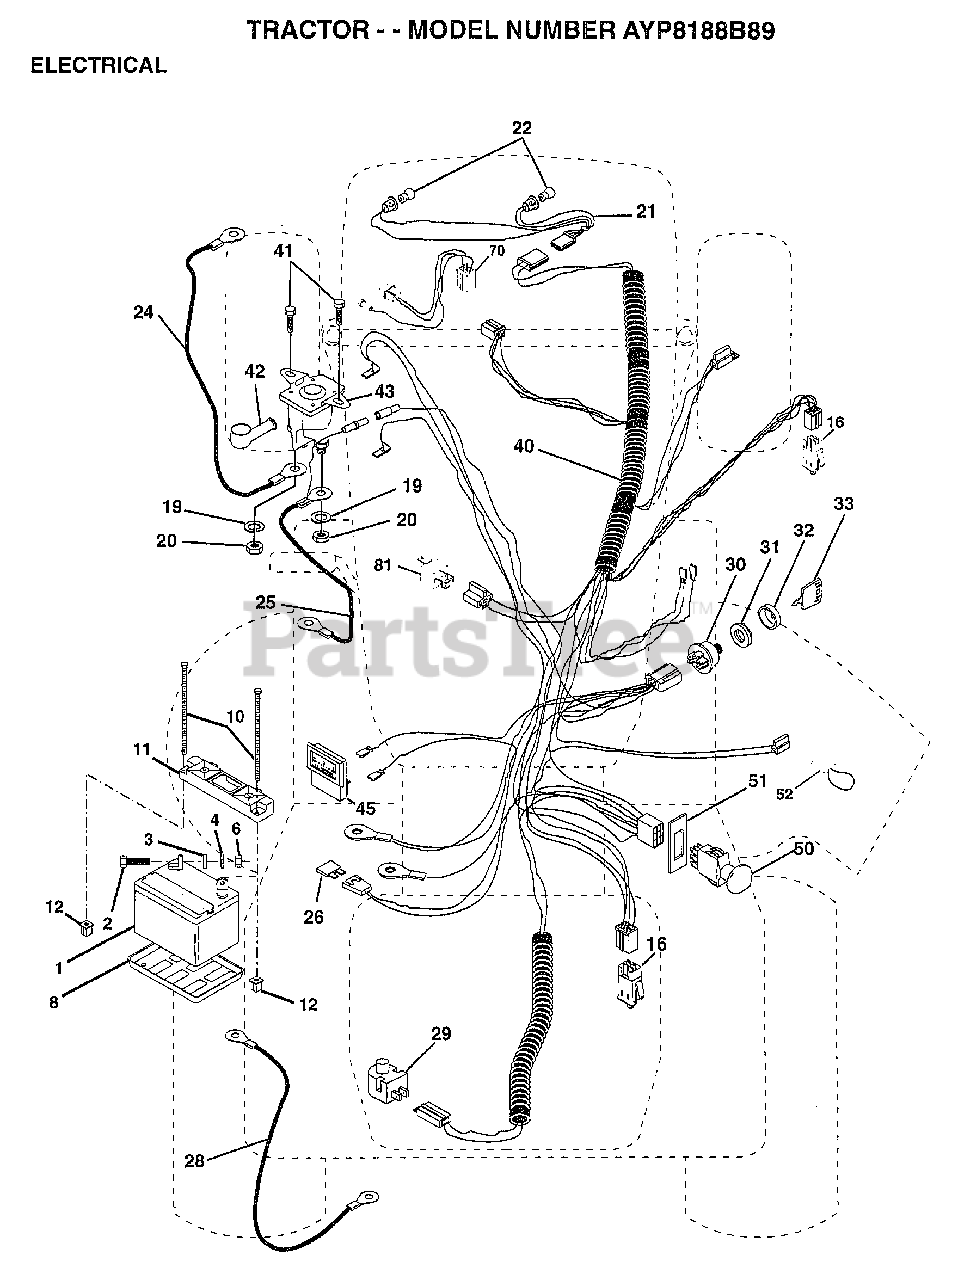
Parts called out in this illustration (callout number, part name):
3	WASHER
4	LOCKWASHER
8	"TRAY T, BATTERY"
11	HOLDDOWN BATTERY
16	SWITCH INTERLOCK
20	NUT
21	"HARNESS,LIGHT SOC"
22	HEADLAMP BULB
24	CABLE-BATTERY T
25	CABLE.6GA.12.5.
26	FUSE HYT
28	CABLE T
29	SWITCH.PLUNGER
30	SWITCH IGN 4POS
31	NUT IGNITION
32	COVER KEY SWITCH
33	KEY
40	HARNESS.IGNITON
41	SCREW
45	AMMETER
50	PTO SWITCH.BLK
51	RING RETAIN PTO
52	PROTECTION LOOP
70	HARNESS.ENGINE
81	RELAY ASSY T
